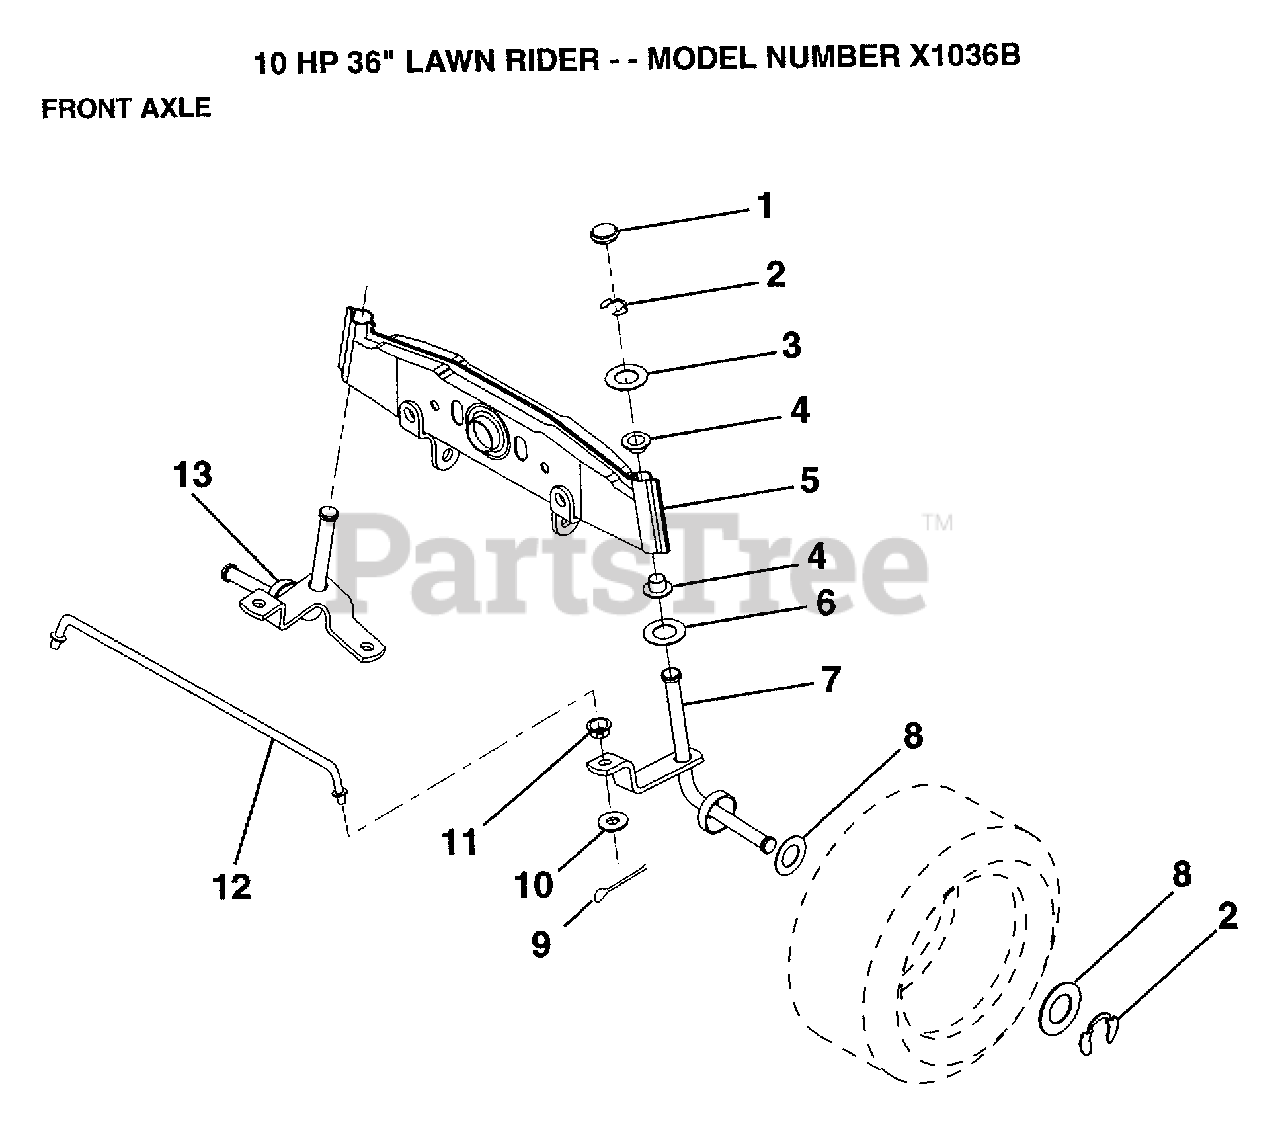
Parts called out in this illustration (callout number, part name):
2	RING
3	WASHER
4	NYLINER
5	AXLE FRONT
6	WASHER .T
7	SPINDLE RH
8	WASHER
9	COTTER PIN
10	WASHER
11	BUSHING.DRAGLINK
12	ROD TIE
13	SPINDLE LH
